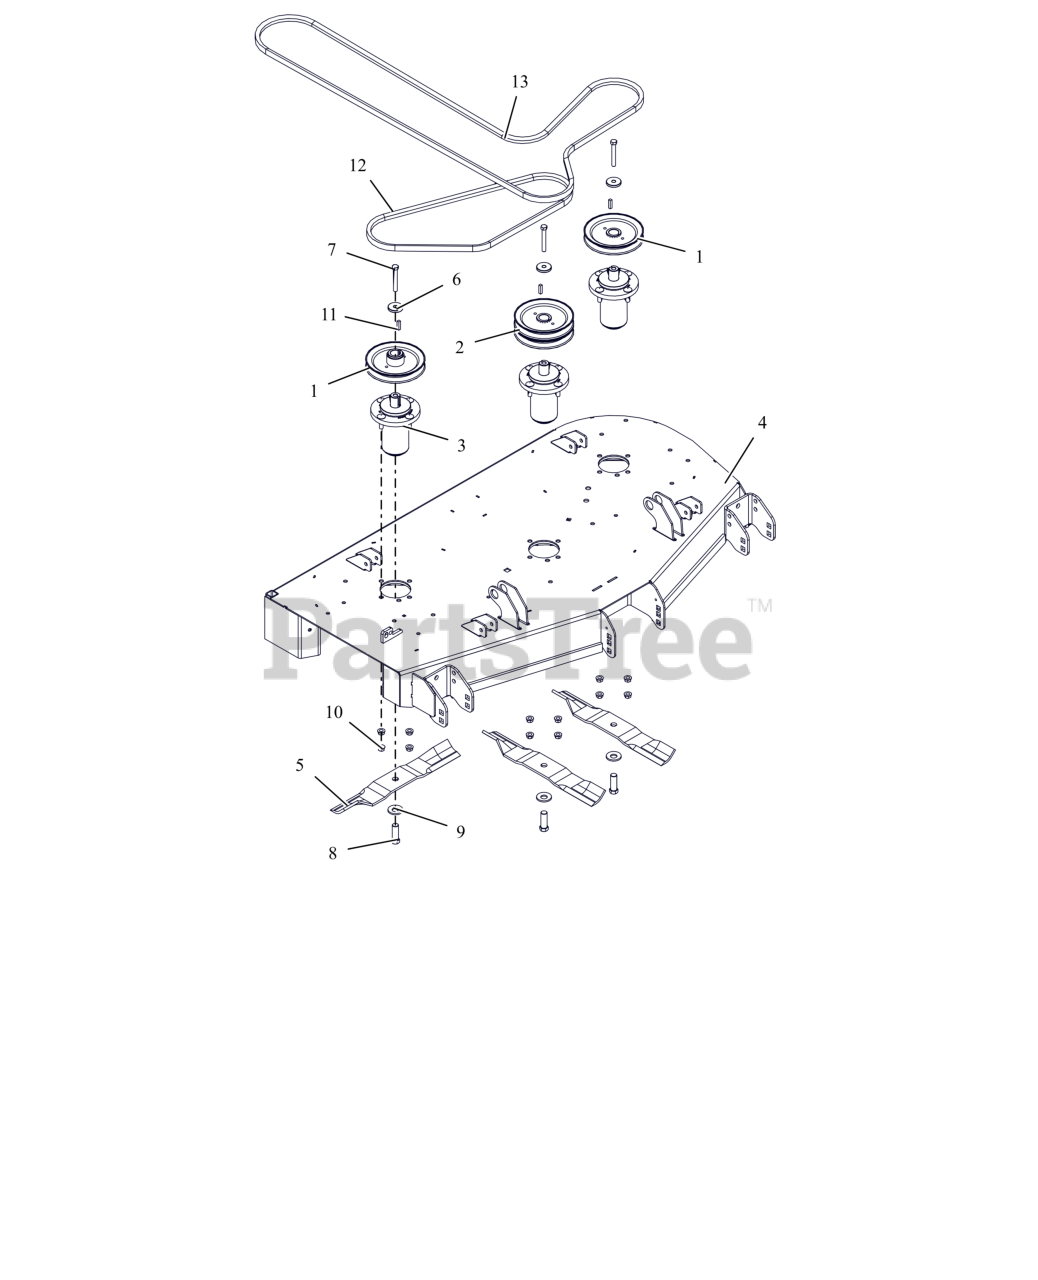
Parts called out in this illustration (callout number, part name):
1	PULLEY, SINGLE-1"ID X 6" OD
2	PULLEY, DOUBLE
3	ASM, MAINT FREE ALUM SPINDLE
4	KIT,DECK-48" W/DECALS - ARIENS
5	BLADE, 16.19" MOWER (HI-LIFT)
6	RETAINER, SHEAVE
7	BLT, HEX .38-16X2.75 G8 ZCC
8	BLT, HEX .62-18X1.75 G8 ZCC
9	WSHR-BLVL .669X1.535X.138
10	NUT-LK-CTR-FLG .375-16 GF ZCC
11	KEY, SQ .25X.25X1.00 RC 40-50
12	V-BELT, B-COGGED
13	V-BELT, HB SECTION
